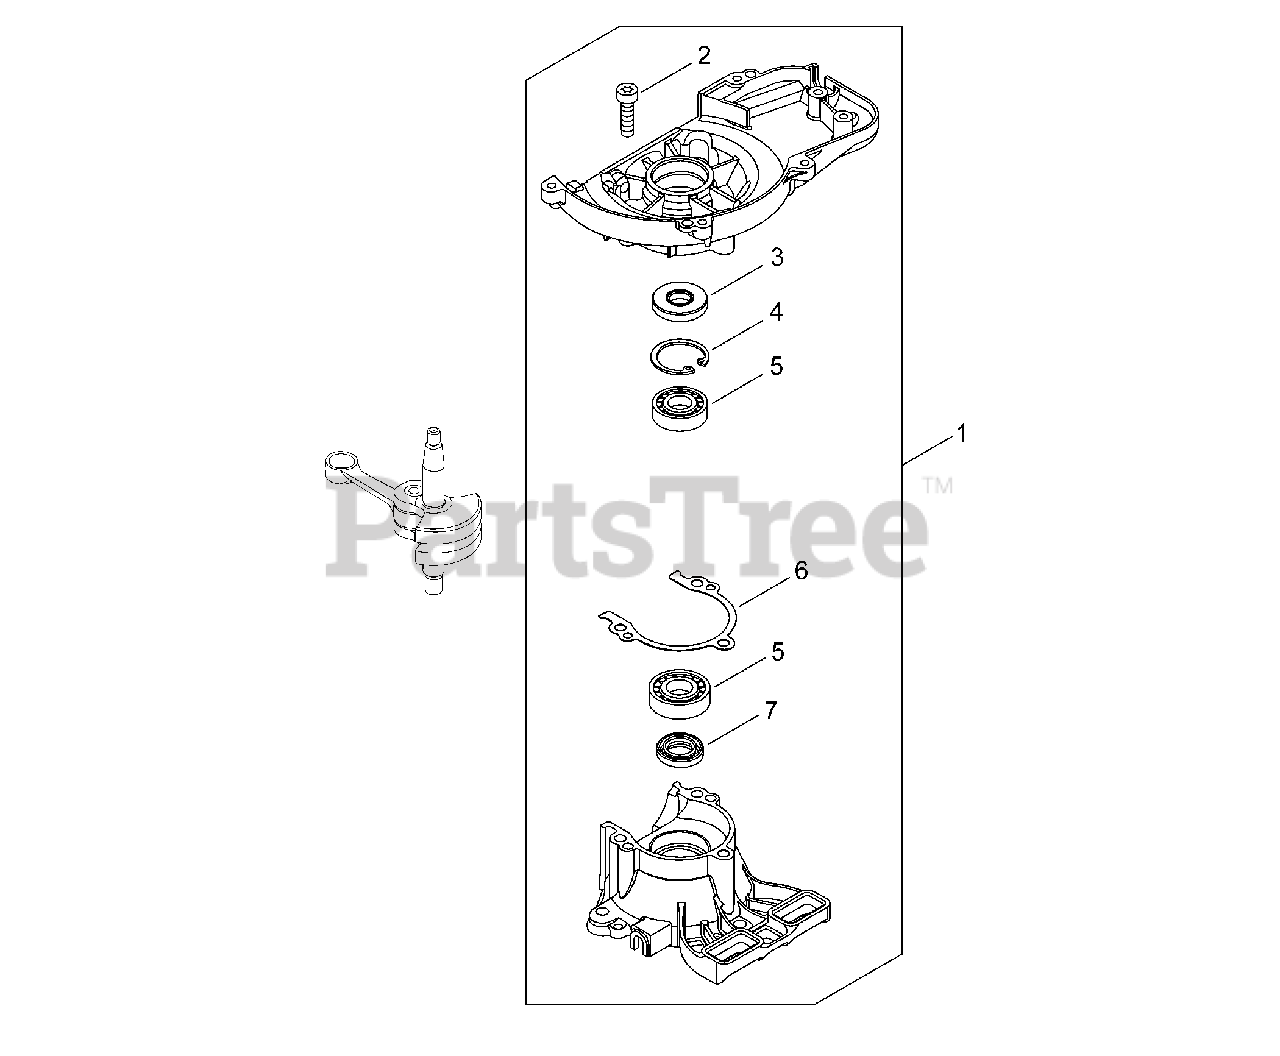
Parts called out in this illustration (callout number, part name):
1	CRANKCASE SET
2	BOLT, TORX 5
4	CIRCLIP 26
5	BEARING, BALL
6	GASKET,CRANKCASE
